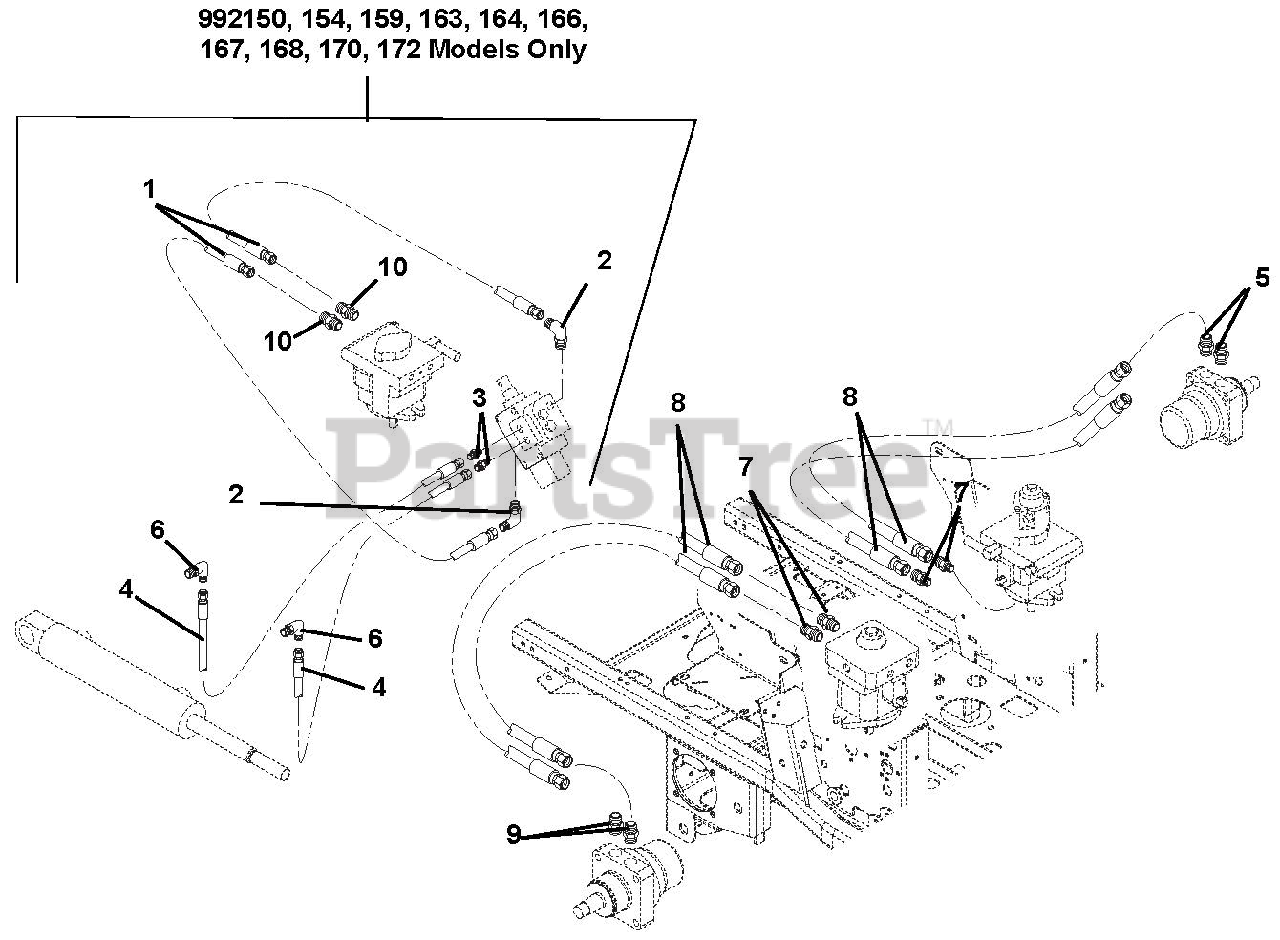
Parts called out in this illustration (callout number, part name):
1	Hose, Hydraulic
2	Hydraulic, Fitting Elbow
3	Adapter
4	Hose, Hydraulic
5	Fitting, Hydraulic Straight
6	Fitting, Hydraulic
7	Adapter, Face Seal 8 x 8 .50 O-Ring
8	Hose, Hydraulic .50
9	Adapter, Hydraulic Steel
10	Fitting, Hydraulic
